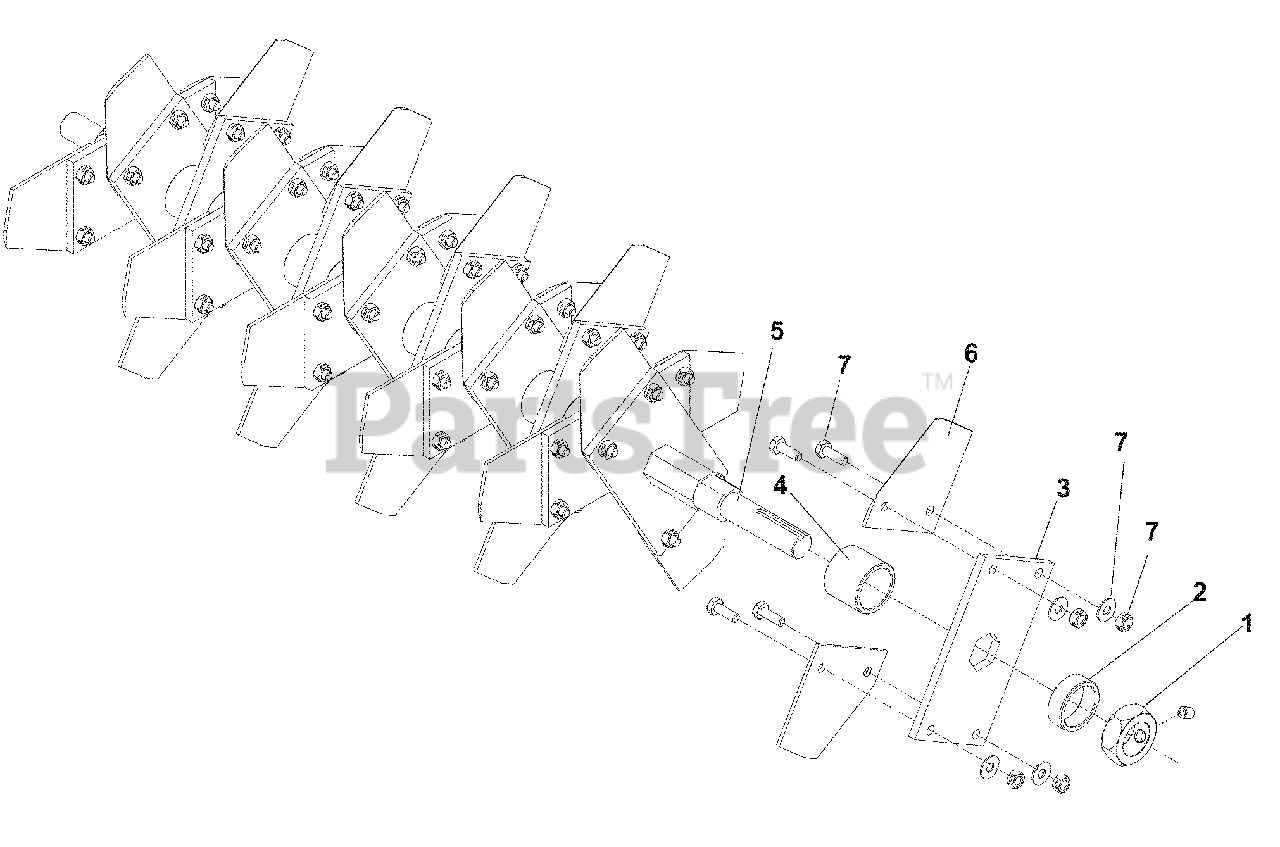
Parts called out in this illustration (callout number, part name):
1	JAM NUT W/SETSCREW
2	END SPACER
3	BLADE MTG. PLATE
4	SPACER - LONG
6	BLADE W/HARDWARE SET (30 BLADES)
7	SCREW & NUT SET (60 EACH)
